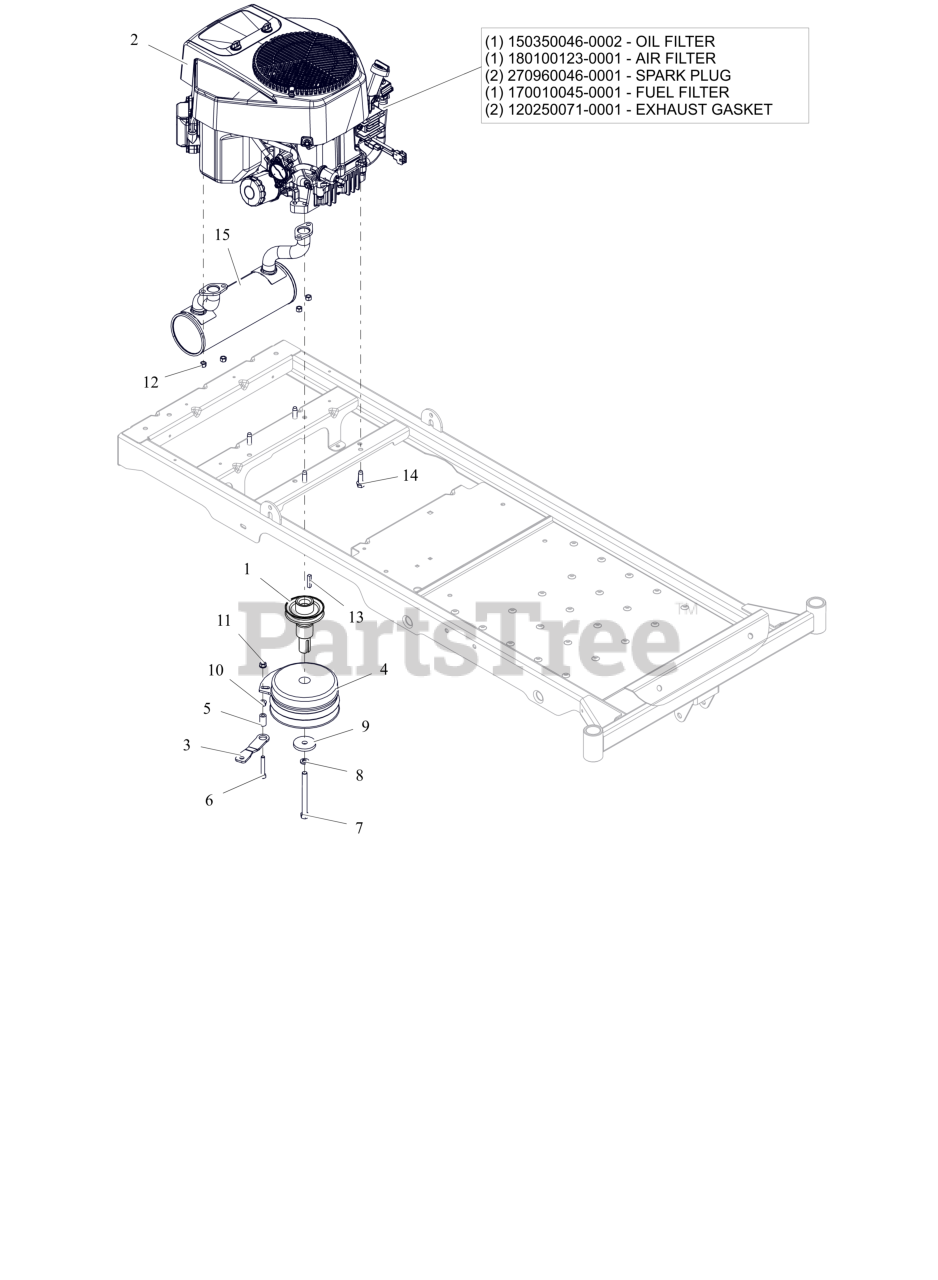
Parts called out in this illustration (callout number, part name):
1	WLDMT, CRANK SHAFT ADAPTER- BRIGGS
2	ENGINE, ARIENS 635cc
2	OIL FILTER
2	AIR FILTER
2	SPARK PLUG
2	FUEL FILTER
2	EXHAUST GASKET
3	BRKT, CLUTCH
4	CLUTCH, 105 FT*LB MONO POLE
5	SPACER, RUBBER 5/16 IDX1.0 LG
6	BLT, HEX .31-18X2.00 G5 ZCC
7	BLT, HEX .44-20X4.50 G8 ZCC NT
8	WSHR, LK-REG .438X.109 ZCC
9	WSHR, FLT .469X2.00X.250 ZCC
10	NUT,SPNLK-FLG .31-18 G5 ZCC
11	NUT,LK-CTR-FLG .31-18 GF ZCC
12	NUT-LK-TOP-FLG M8 ZCC
13	KEY-SQ .25 X 1.25 X .25 SAE
14	SCR,TAP .375-16X1.25HWH TR ZCC
15	WLDMT, LONCIN MUFFLER 635CC
